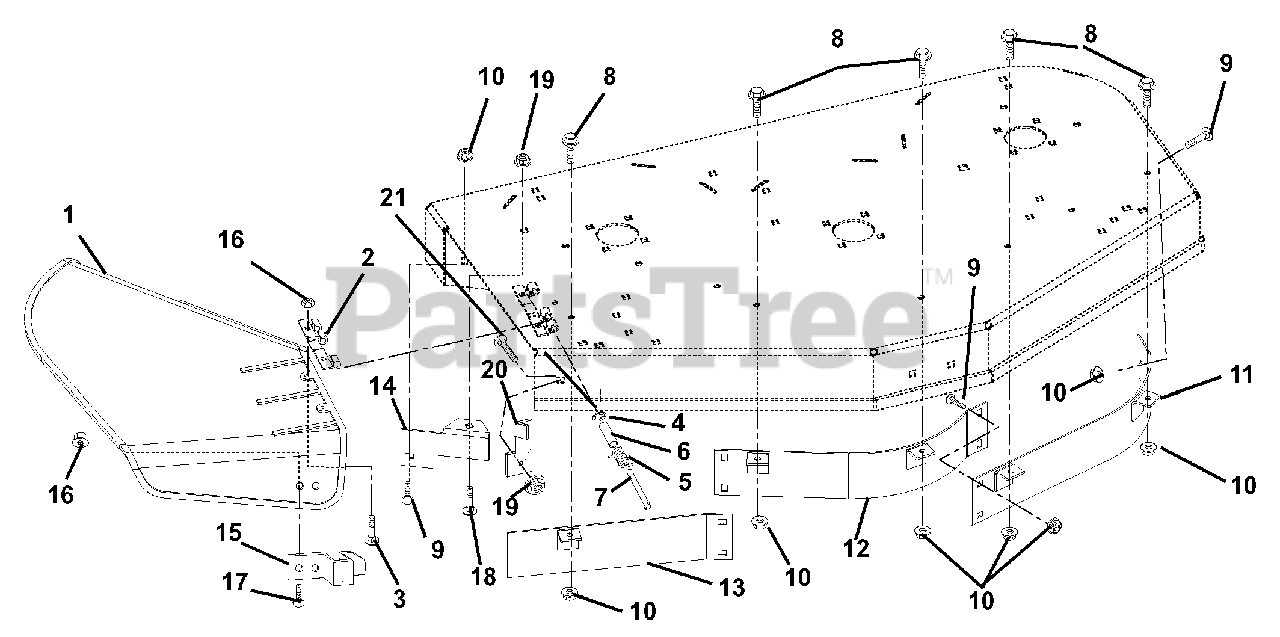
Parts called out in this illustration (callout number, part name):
1	DEFLECTOR, CHUTE
2	HINGE PLATE
3	@BLT-RDHDSQNK .25-20X.75 G5YZ
4	RG-RTNG-EXT .312X.025
5	SG-TORS .095X.50X 1.0
6	BSHG-SLV .334 X .502 X 1.437
8	BLT-SERHFWH .312-18X.75 YWZC
9	@BLT-RHDSSQNK .31-18X.75 G5YZ
10	@NUT-LK-NYL-FLG .31-18 YWZC
11	BAFFLE - LEFT FRONT - 40"
12	BAFFLE - CENTER FRONT - 40"
13	BAFFLE - RIGHT FRONT - 40"
14	DEFLECTOR-40"
15	FLAT SPRING
16	@NUT-LK-TOP-FLG .25-20 YWZC
17	@BLT-RDHDSQNK .25-20X.50 G5YZ
18	@BLT-RDHDSQNK .38-16X1.00 G5YZ
19	@NUT-LK-NYL-FLG .38-16 YWZC
20	BRACKET, CHUTE LOCK
21	@BLT-RDHDSQNK .38-16X1.50 G5YZ
